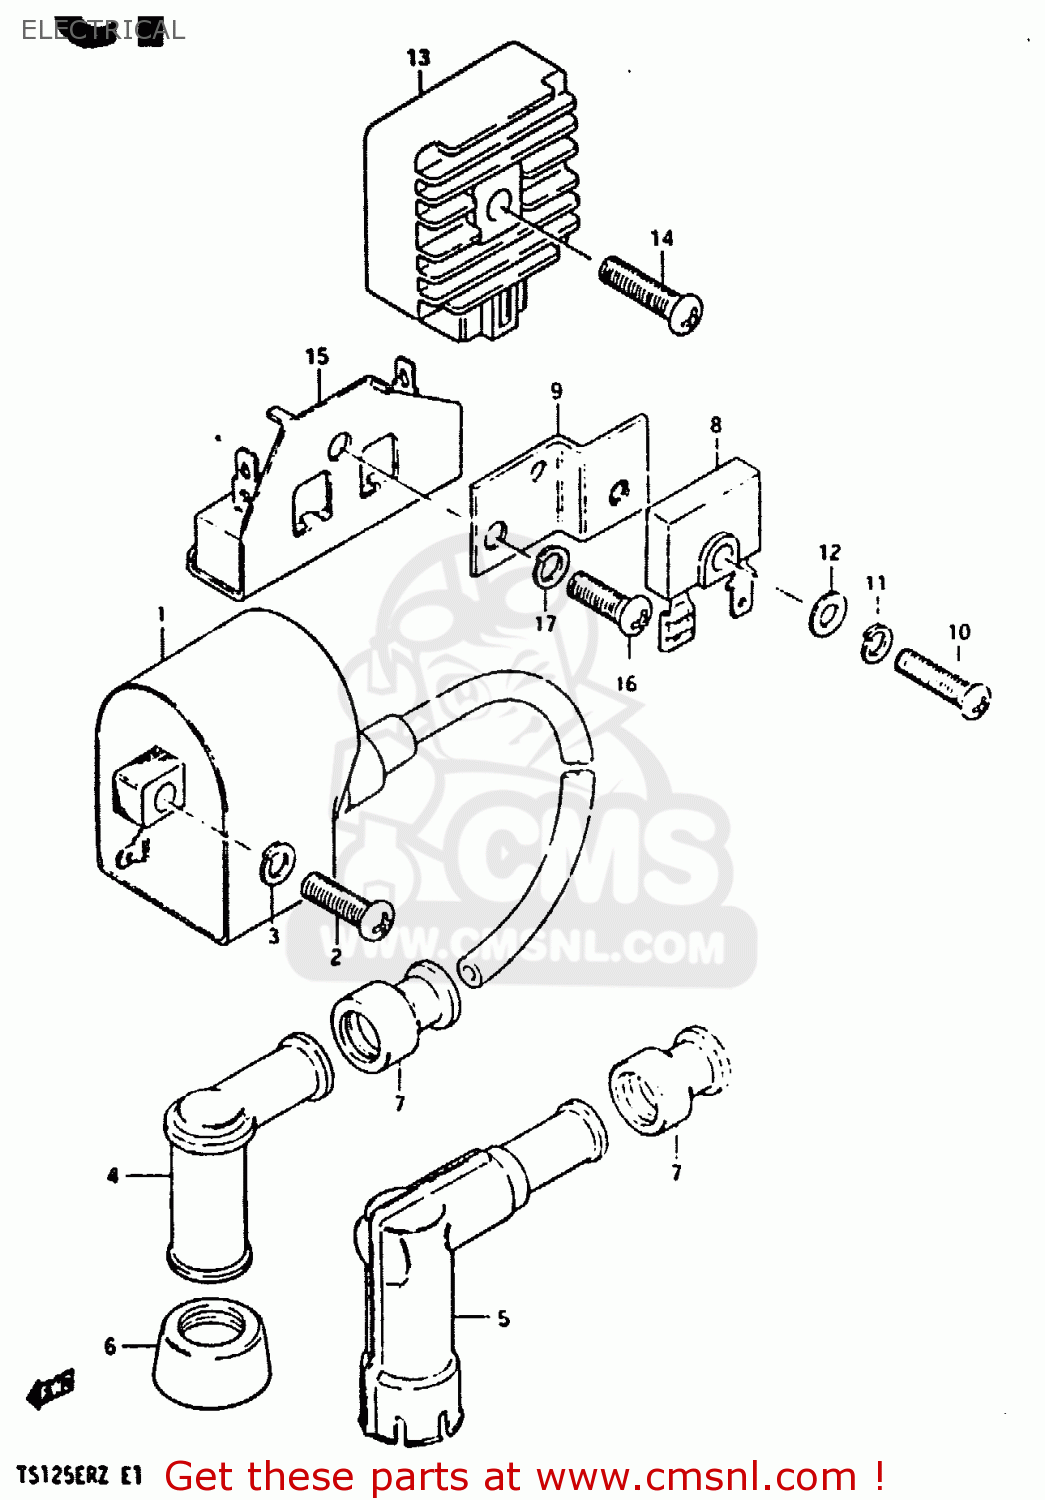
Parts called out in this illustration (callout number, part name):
1	UNIT & COIL ASSY,IGNITION
2	SCREW
3	LOCK WASHER
5	CAP,SPARK PLUG
7	SEAL,SPARK PLU
8	RECTIFIER ASSEMBLY
9	PLATE, RECTIFIER
10	SCREW 5X20
11	LOCK WASHER
12	WASHER
13	RECTIFIER ASSY,REGULATOR
14	SCREW
